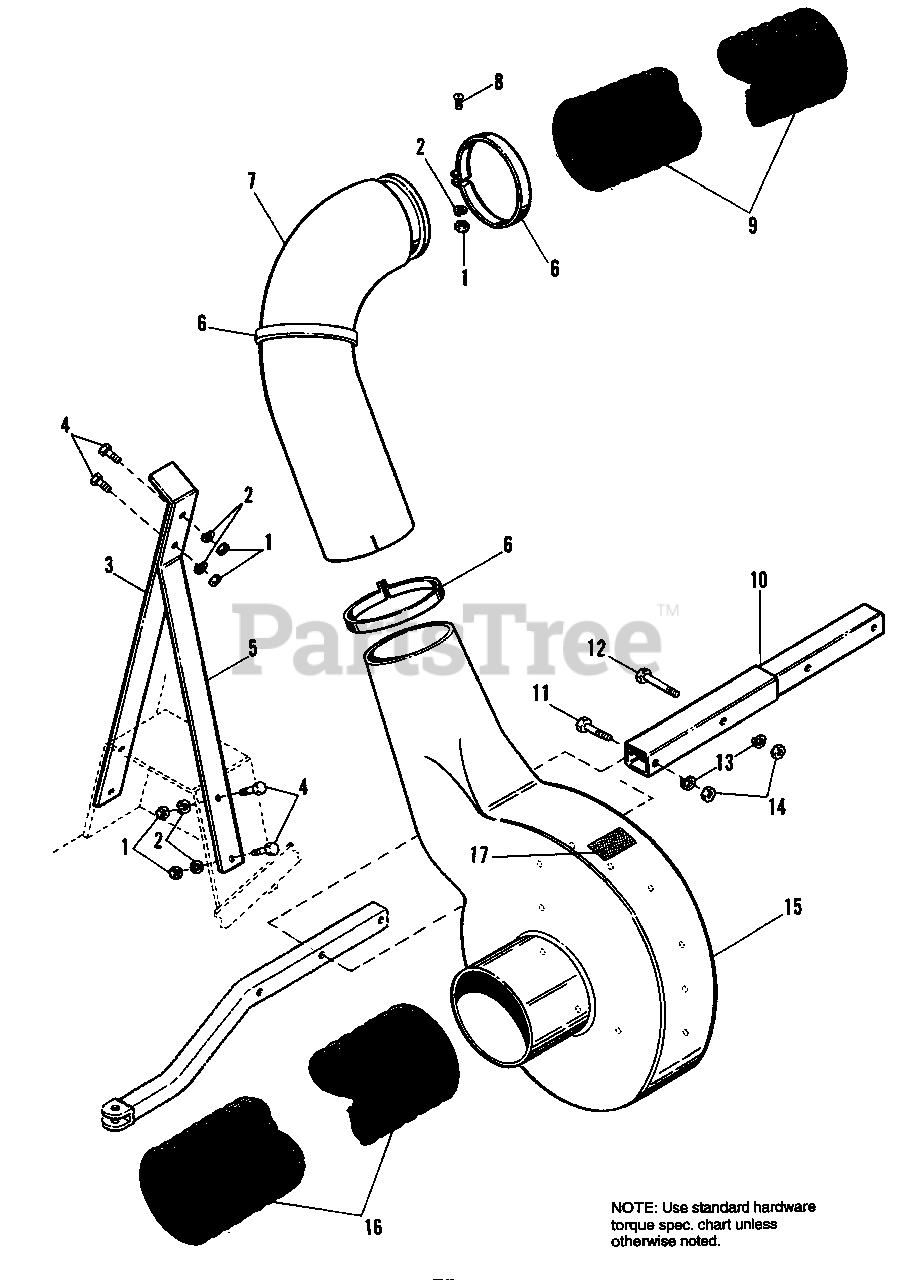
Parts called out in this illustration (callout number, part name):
1	NUT, Hex, 1/4-20 Std.
2	WASHER, Lock, 1/4 Std.
3	SUPPORT, R.H., Outlet Tube
4	CAPSCREW, Hex Hd., 1/4-20 x 3/4
5	SUPPORT, L.H., Outlet Tube
6	CLAMP, Hose, 6" Dia.
7	ELBOW, Blower Housing
8	SCREW, Mach. Rd. Hd., 1/4-20 x 3
9	HOSE, Exhaust, 6" Dia. x 44" Long
10	HITCH EXTENSION ASSY.
11	CAPSCREW, Hex Hd., 3/8-16 UNC x 2
12	CAPSCREW, Hex Hd., 3/8-16 UNC x 2-1/2
13	WASHER, Lock, 3/8 Std.
14	NUT, Hex, 3/8-16 UNC
15	HOUSING, Fan
16	HOSE, Inlet, 7" Dia. x 44" Long
17	DECAL, Caution
